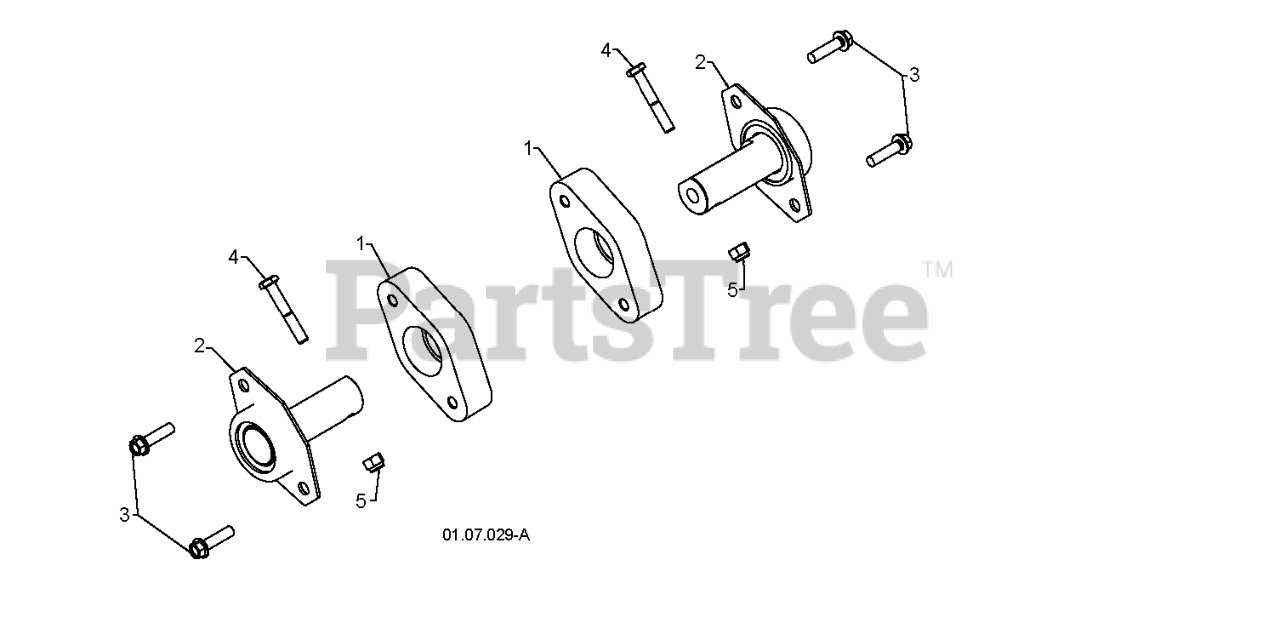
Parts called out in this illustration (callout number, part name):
1	BEARING RETAINER, PLASTIC
2	BEARING.BALL.AUGER.FLAT.
3	SCREW, HEX HD 5/16X1
4	SCREW.HEX.HD1/4-20X
5	LOCKNUT.NYLOC.1/4-20
